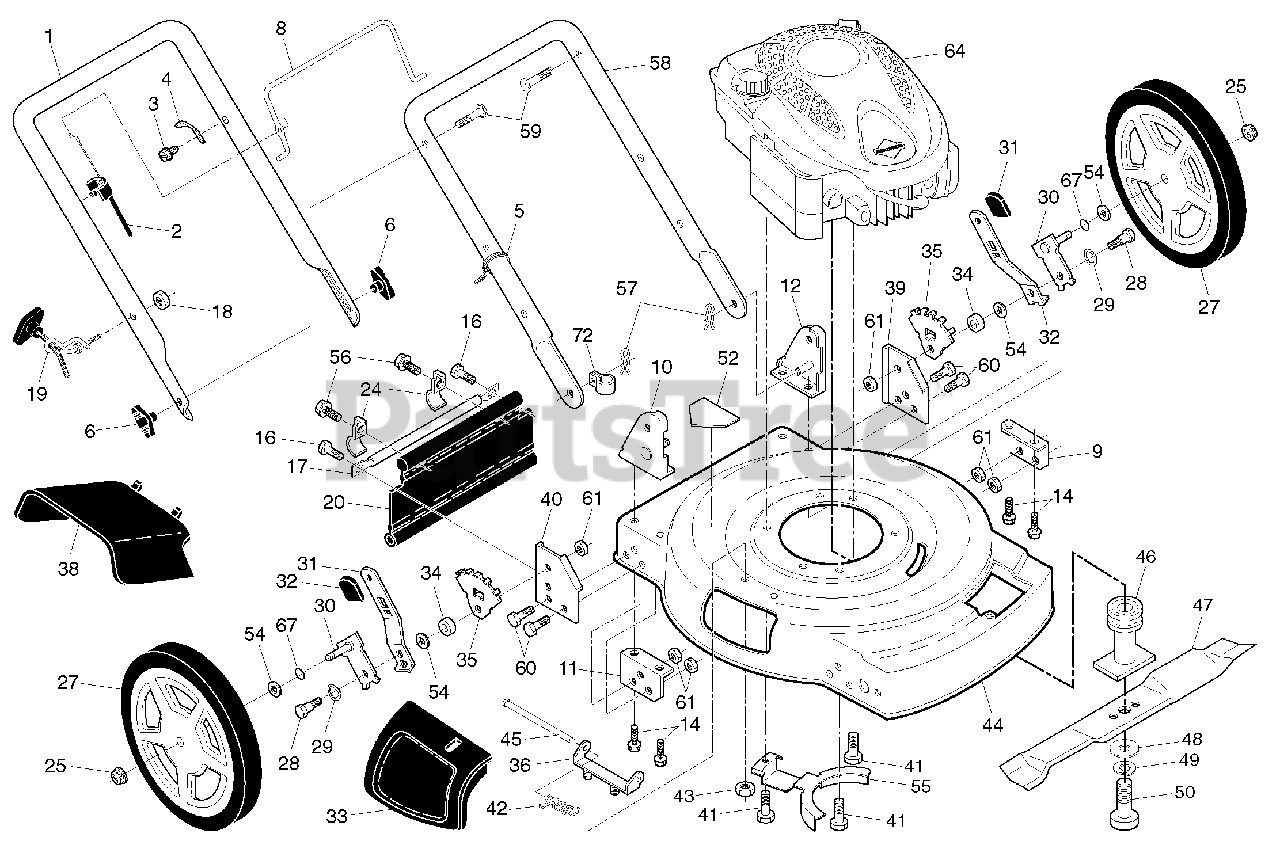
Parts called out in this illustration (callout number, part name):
1	Upper Handle
2	Engine Zone Control Cable
3	Screw
4	Bracket, Upstop
5	Wire Tie
6	Handle Knob
8	Control Bar
9	Support Bracket, Handle, LH
10	Handle Bracket, RH
11	Support Bracket, Handle, RH
12	Handle Bracket, LH
14	Screw, Thread Cutting 5/16-18 x 3/4
16	Screw
17	Support Rod
18	Locknut, Keps
19	Rope Guide
20	Rear Skirt
24	Clamp, Rear Skirt
25	Locknut, Hex 3/18-16
27	Wheel & Tire Assembly
28	Shoulder Bolt
29	Washer, Curved, Cylindrical
30	Axle Arm Assembly
31	Knob, Selector
32	Spring, Selector
33	Mulcher Door
34	Spacer
35	Bracket, Wheel Adjuster
36	Bracket, Housing
38	Deflector, Discharge
39	Support Bracket, LH
40	Support Bracket, RH
41	Screw, Hex Head, Threaded, Rolled 3/8-16 x 1-1/8
42	Spring, Torsion
43	Locknut, Hex
44	Kit, Lawn Mower Housing
45	Rod, Hinge
46	Blade Adapter / Pulley
47	Blade, 22"
48	Washer, Hardened
49	Washer, Lock, Helical
50	Screw, Hex Head, Grade 8 3/8-24 x 1-3/8
52	Decal, Danger
54	Washer, Flat
55	Belt Keeper
56	Screw, Hex Washer Head #10-24 x 1/2
57	Hairpin Cotter
58	Lower Handle
59	Handle Bolt
60	Bolt
61	Locknut
67	O-Ring
72	Clip, Cable
72	Operator's Manual, English
72	Operator's Manual, French
72	Repair Parts Manual
